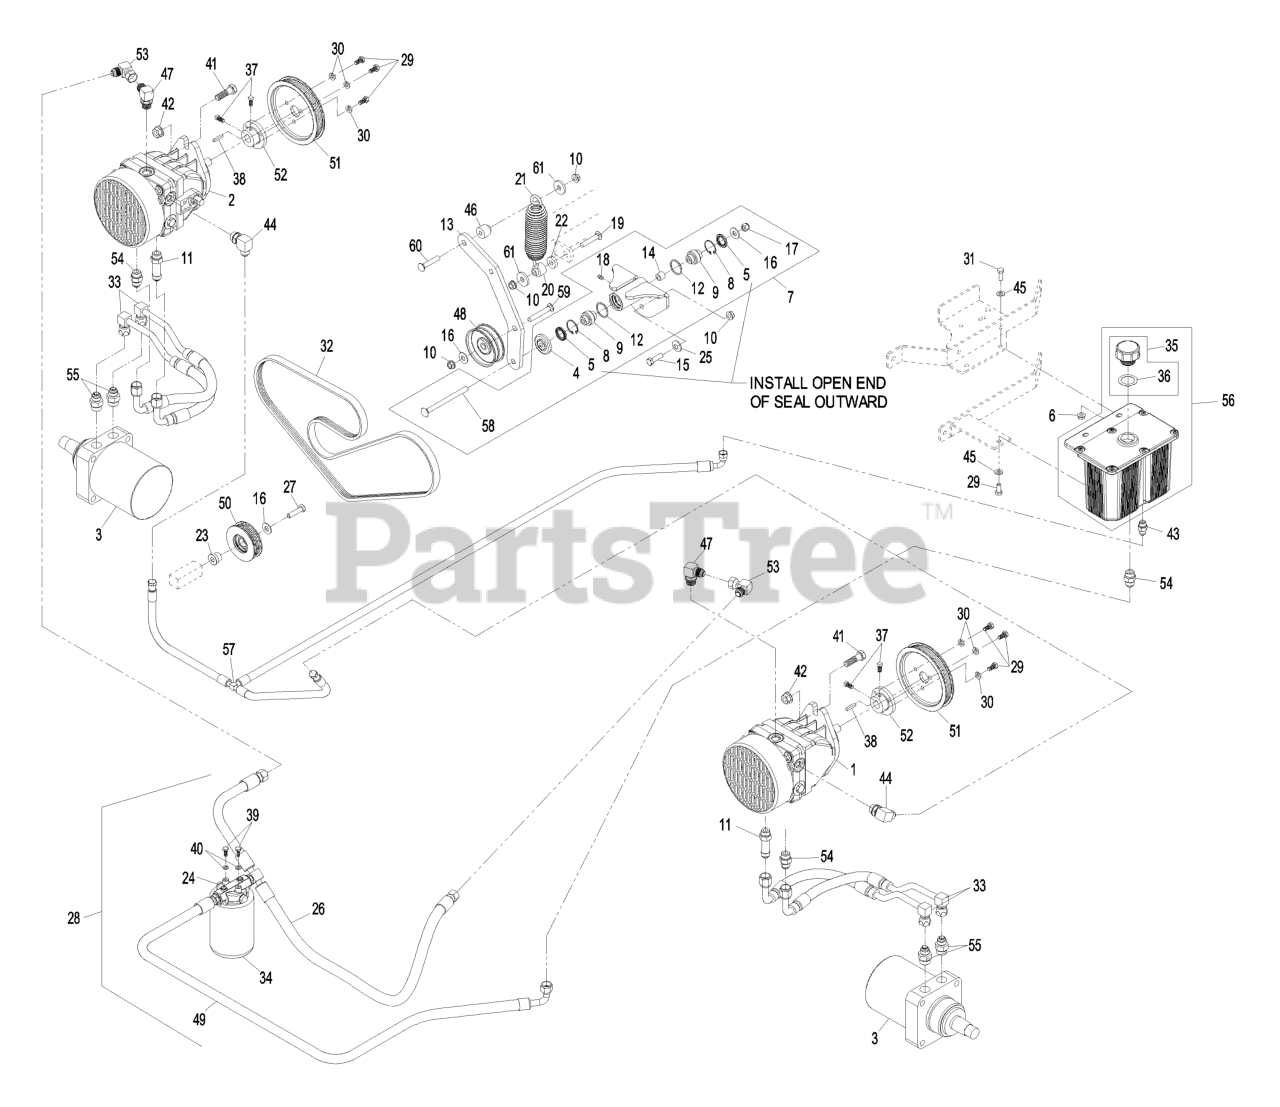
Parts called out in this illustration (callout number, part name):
4	GUARD-TOP
5	SEAL-LIP, SINGLE
7	KIT,XS PUMP IDLER
8	RING-SNAP
9	BEARING-SPHERICAL
10	NUT-HHF, WHIZ
11	ADAPTER-STR, LONG
13	ARM, XS HYDRO TIGHTENER
15	SCREW-HH
16	WASHER-FLAT
17	NUT-LOCK, NI
18	FITTING-GREASE
19	BOLT-CARR, SHORT NECK
20	SPACER-SPRING, FAN PUMP
22	SPACER-BRACKET, GUIDE
23	SPACER,LOWER FRAME IDLER
24	HEAD-FILTER
25	WASHER-BELLEVILLE
26	HOSE,31 EPS PUMP INLET
27	SCREW-HH
29	SCREW-HH
30	WASHER-LOCK
31	SCREW-HH
32	BELT,PVK 5 X 70.5
33	HYD HOSE ASM
34	FILTER,XP HYD 25 MICRON
35	KIT,HYD RES CAP W/GASKET
36	GASKET-CAP
37	SCREW-SET
39	SCREW-HH
40	WASHER-LOCK
41	SCREW-HH
42	NUT-HHF
43	FITTING-STRAIGHT
44	FITTING-ELBOW, 90 DEG
45	WASHER-PLAIN
47	FITTING-90 DEG
48	IDLER,PUMP
50	ASM,LOWER FRAME IDLER
51	SHEAVE,5K 5.6" PD POLY-V
52	HUB-PUMP
53	FITTING-90 DEG
54	FITTING-STRAIGHT
55	FITTING-STRAIGHT
56	HYDRAULIC TANK ASM
57	ASM,CASE DRAIN HOSE
58	BOLT CARR 3/8-16X5
59	SCREW-CARR
60	SCREW-CARR
